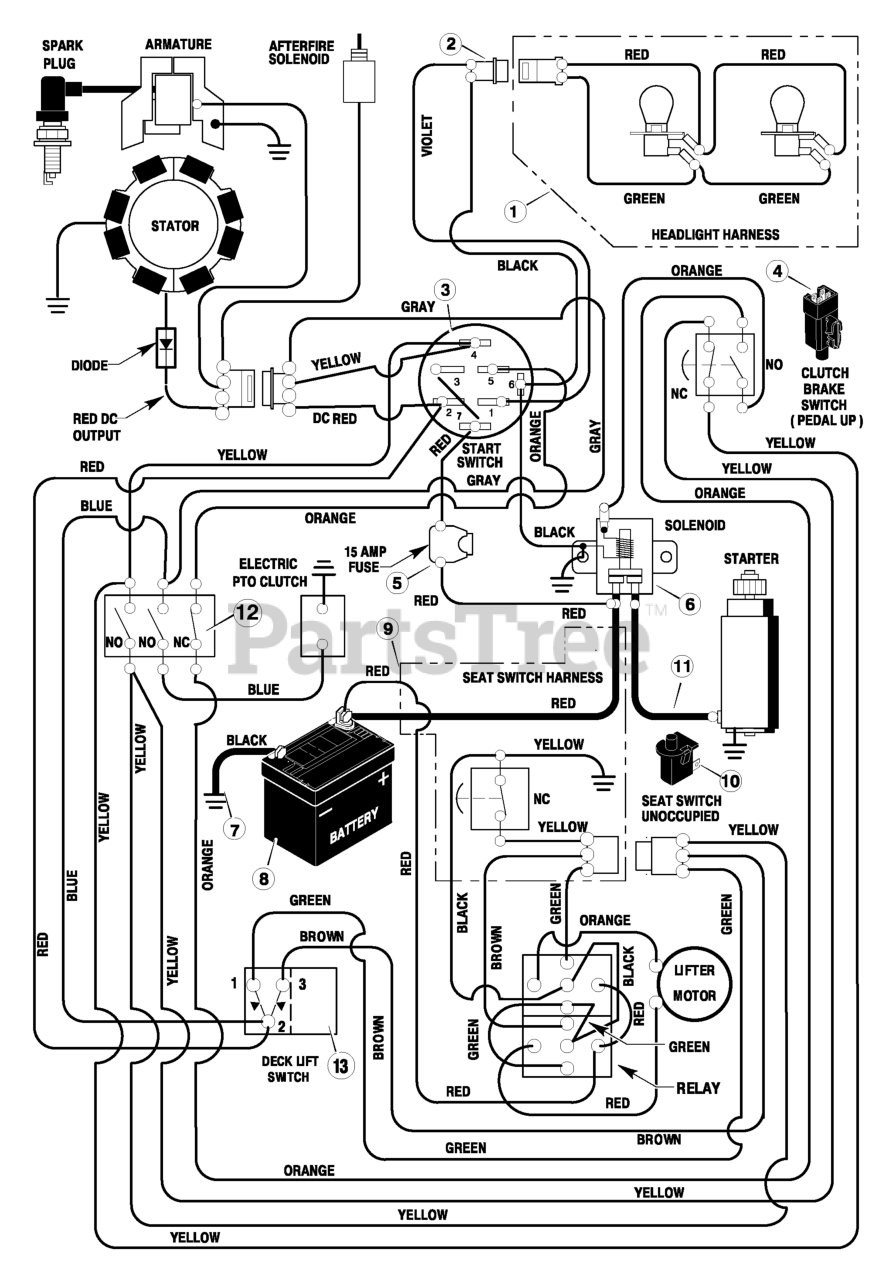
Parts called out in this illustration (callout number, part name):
1	Harness, Light Wire
2	Harness, Chassis Wire
3	Switch, Ignition
4	Switch, Limit
6	Solenoid
7	Cable, Battery Ground
8	Battery
9	Harness, Seat Switch Wire
10	Switch, Seat Sensor
12	Switch, Electric PTO
13	Switch, Lifter
